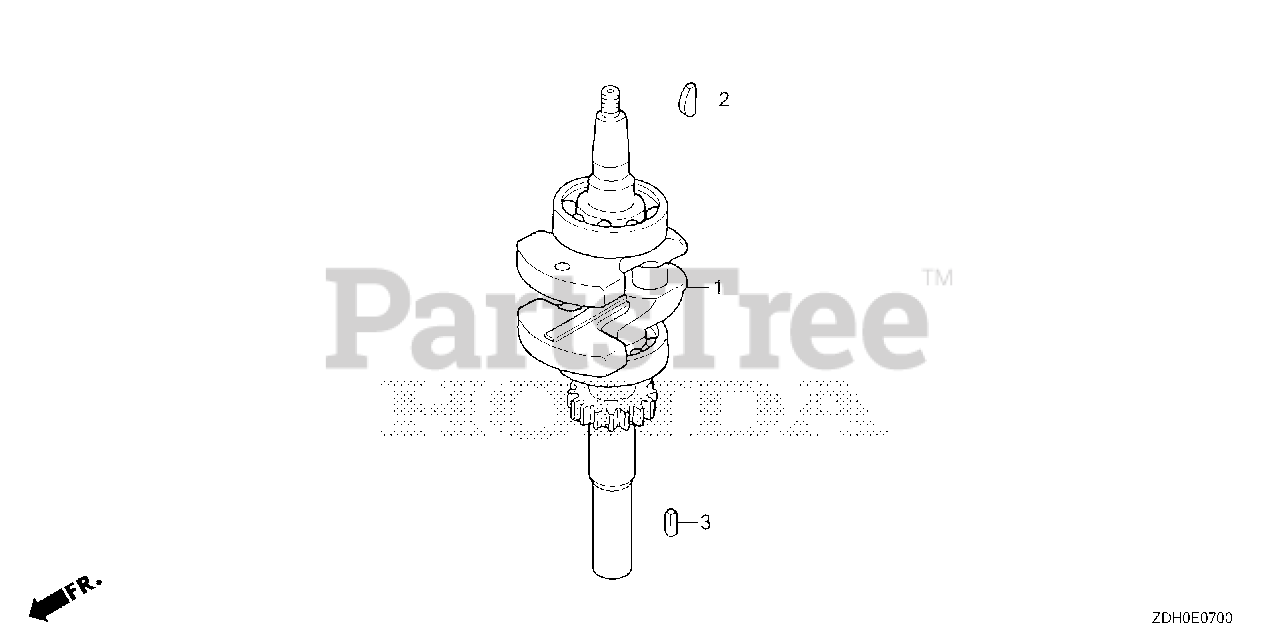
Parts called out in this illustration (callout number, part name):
1	CRANKSHAFT
2	KEY, SPECIAL
3	KEY (5MM)
